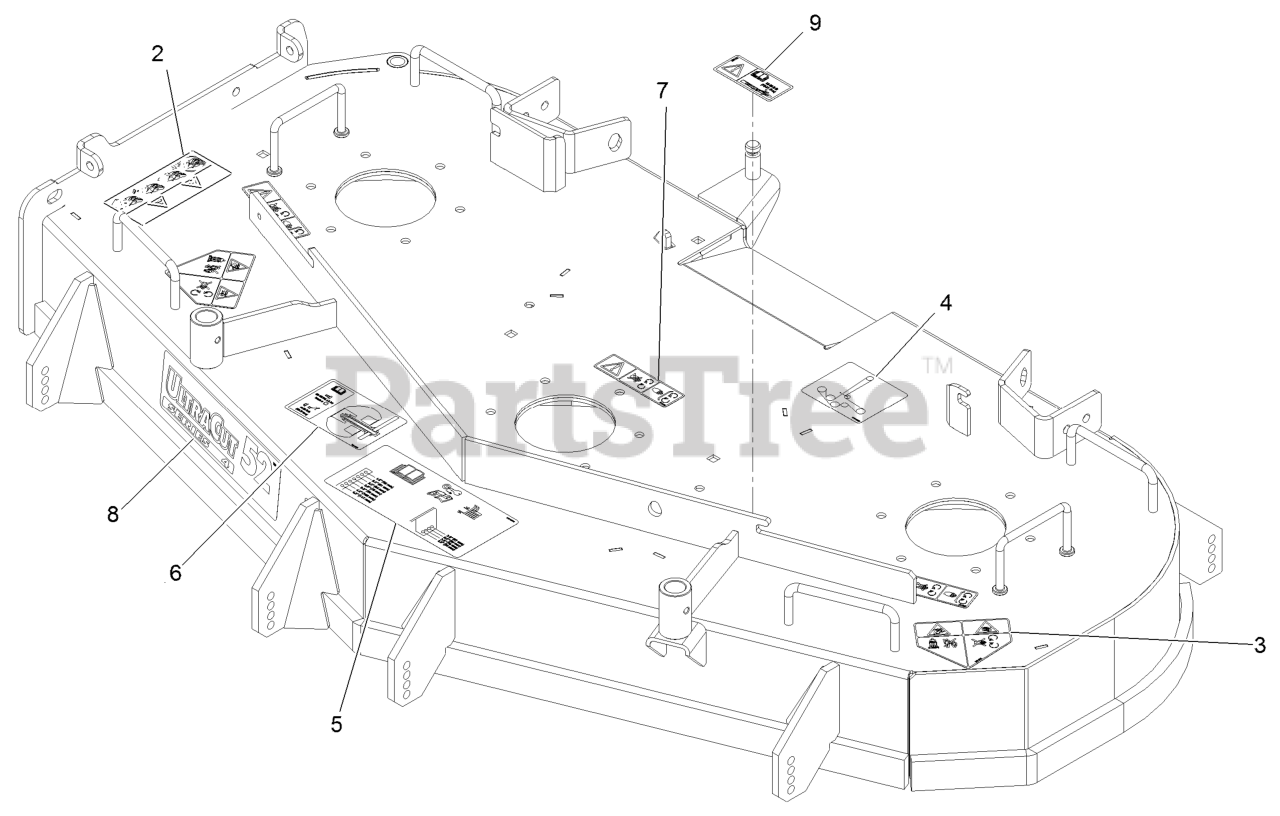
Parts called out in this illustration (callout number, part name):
2	DECAL-WARNING, BAGGER
3	DECAL-DANGER
4	DECAL-BELT ROUTING
5	DECAL-ANTI-SCALP
6	DECAL-ROLLER MOUNTING
7	DECAL-COVER, MISSING
8	DECAL,ULTRACUT 52 SERIES
9	DECAL-BOLT TORQUE
